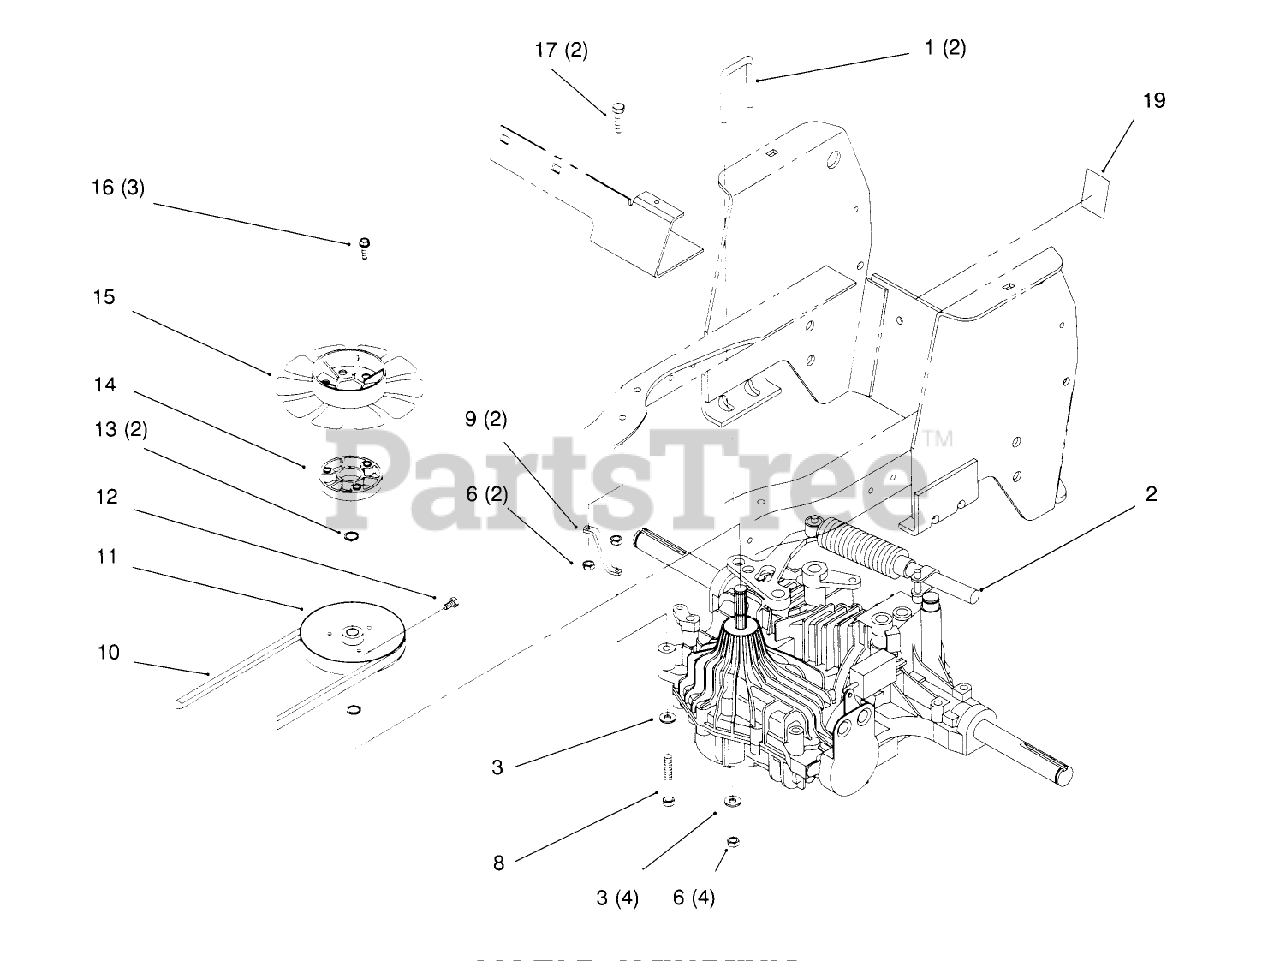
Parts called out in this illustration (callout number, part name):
1	U-BOLT
3	WASHER-PLAIN
6	NUT-LOCK, NI
8	SCREW-HH
9	Strap-Torque (Only On: 72043,72063,72103)
11	PULLEY-HYDRO TRANS
12	SCREW-HSH
13	RING-RETAINING
14	SPACER - FAN
15	FAN - HYDRO
16	SCREW-HWHTF
17	SCREW-HH
19	DECAL-VALVE, HYDRO
19	DECAL-BYPASS VALVE
